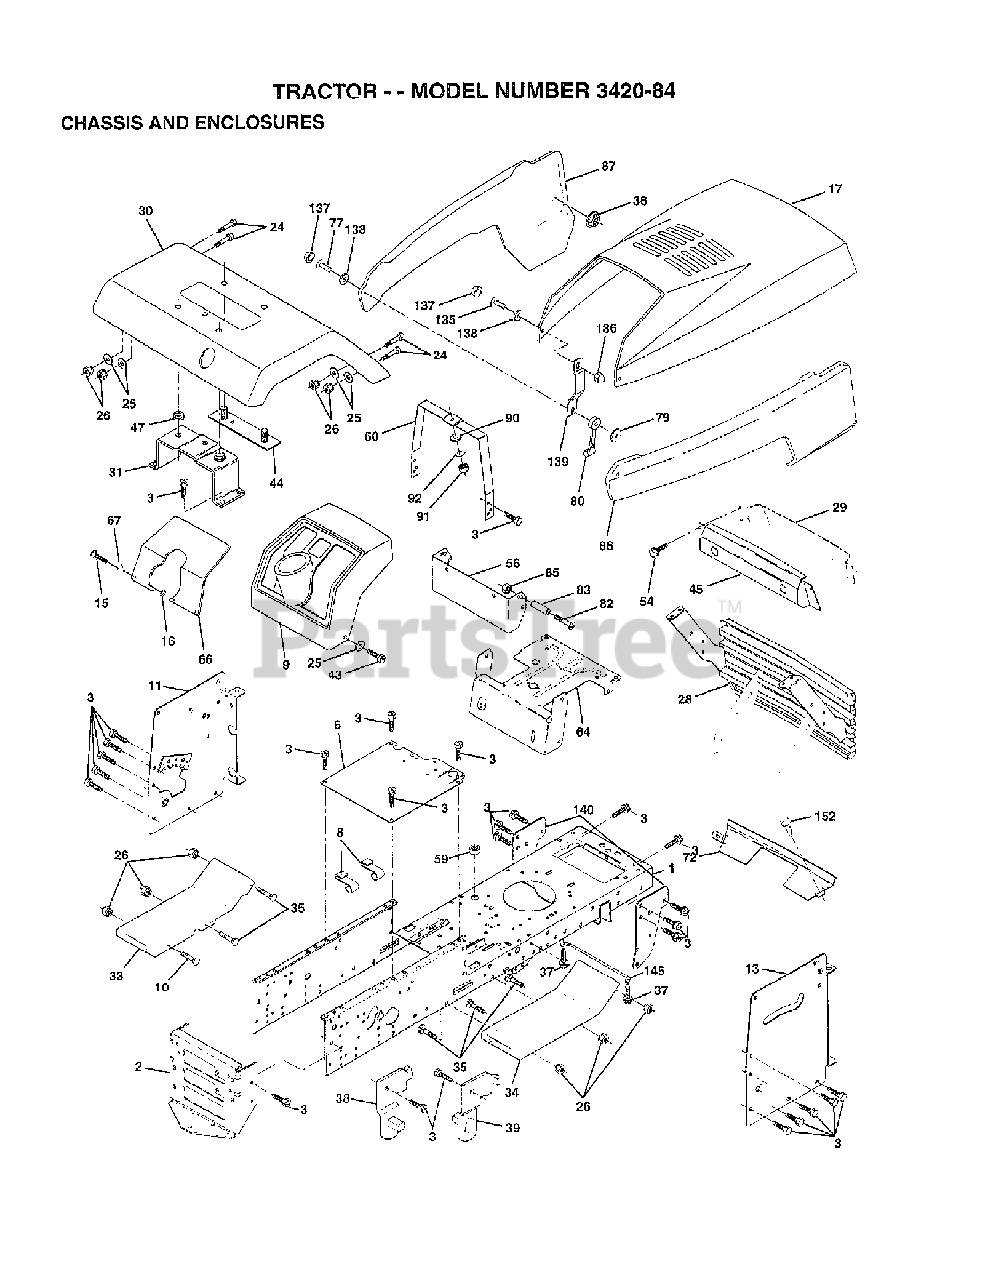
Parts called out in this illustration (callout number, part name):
6	SADDLE FLAT
8	CLIP,INSULATOR
13	Poulan TBD
17	Poulan TBD
25	WASHER
26	NUT
30	Poulan TBD
31	FENDER BRKT
33	Poulan TBD
34	Poulan TBD
36	PAL NUT LT
37	SCREW LT
38	BRACKET LH PIVOT
39	BRACKET RH PIVOT
43	SCREW GTV
44	STRAP-FENDER YT
47	NUT-PUSH YT
50	DASH SUPT YP
54	SCREW.HEX.WS.HD.8-18 X 7/8
64	DASH LOWER LT
66	Poulan TBD
67	WASHER
72	Poulan TBD
77	SCREW
79	NUT.WELD
80	LATCH.HOOD.
82	SCREW
83	SPACER LT
85	NUT **
86	Poulan TBD
87	Poulan TBD
90	WASHER PM
91	NUT
92	LOCKWASHER
135	SCREW 10-24X3/8
136	NUT
137	SNAP CAP LT
138	WASHER LT
139	BRACKET.SUPPORT.HOOD/PANEL.NLA
140	BRACKET SUSPENSION FRONT
